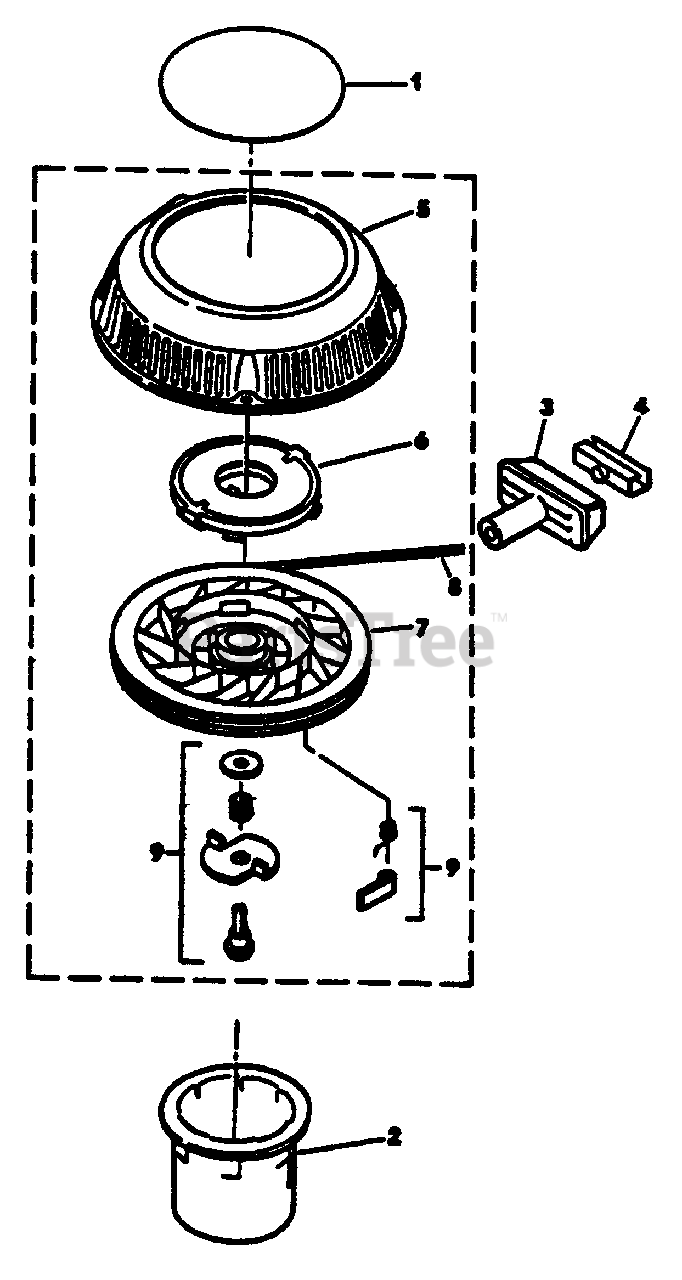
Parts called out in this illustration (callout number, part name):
1	Decal
2	Starter Hub (680527 & 680528 Only)
3	Starter Handle
4	Rope Clip-Starter Insert
5	Starter Housing and Shaft
6	Recoil Spring and Keeper
7	Pulley
8	Rope
9	Dog Kit
